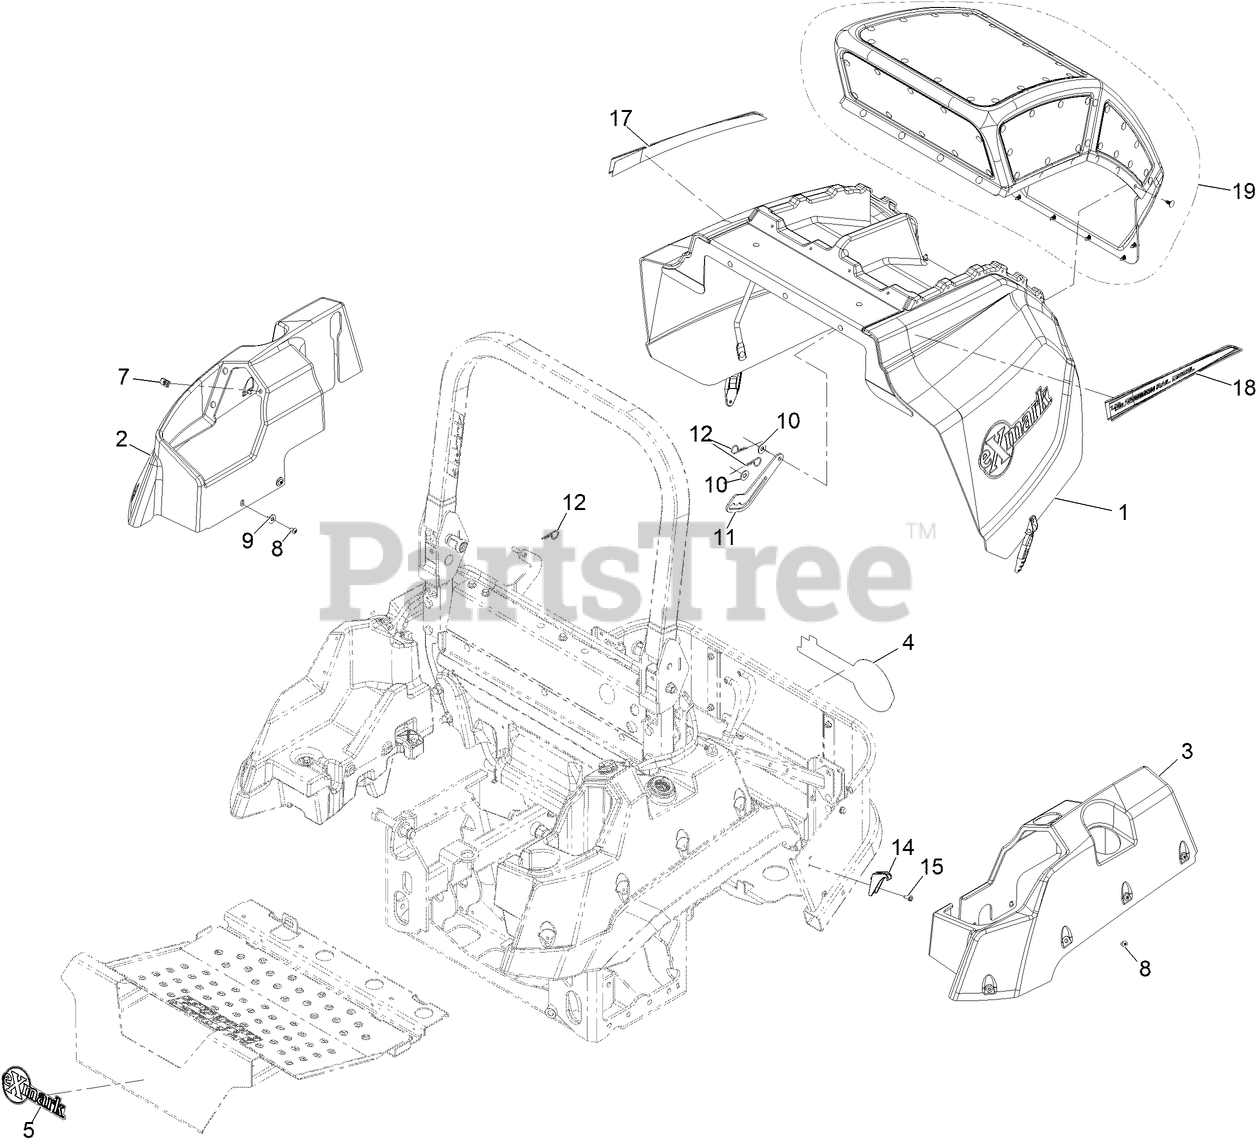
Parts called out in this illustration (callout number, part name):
1	ASM, HOOD LZSD
2	COVER-TANK, RH
3	COVER-TANK, LH
4	DECAL-EXMARK
5	DECAL-EXMARK
8	SCREW-TORX
9	WASHER-FLAT
10	WASHER-FLAT
11	PROP-HOOD
12	PIN-COTTER, HAIR
14	LATCH-CATCH
15	SCREW-HWH
17	DECAL-COMMON RAIL DIESEL-RH
18	DECAL-COMMON RAIL DIESEL-LH
19	ASM, HOOD-INTAKE
